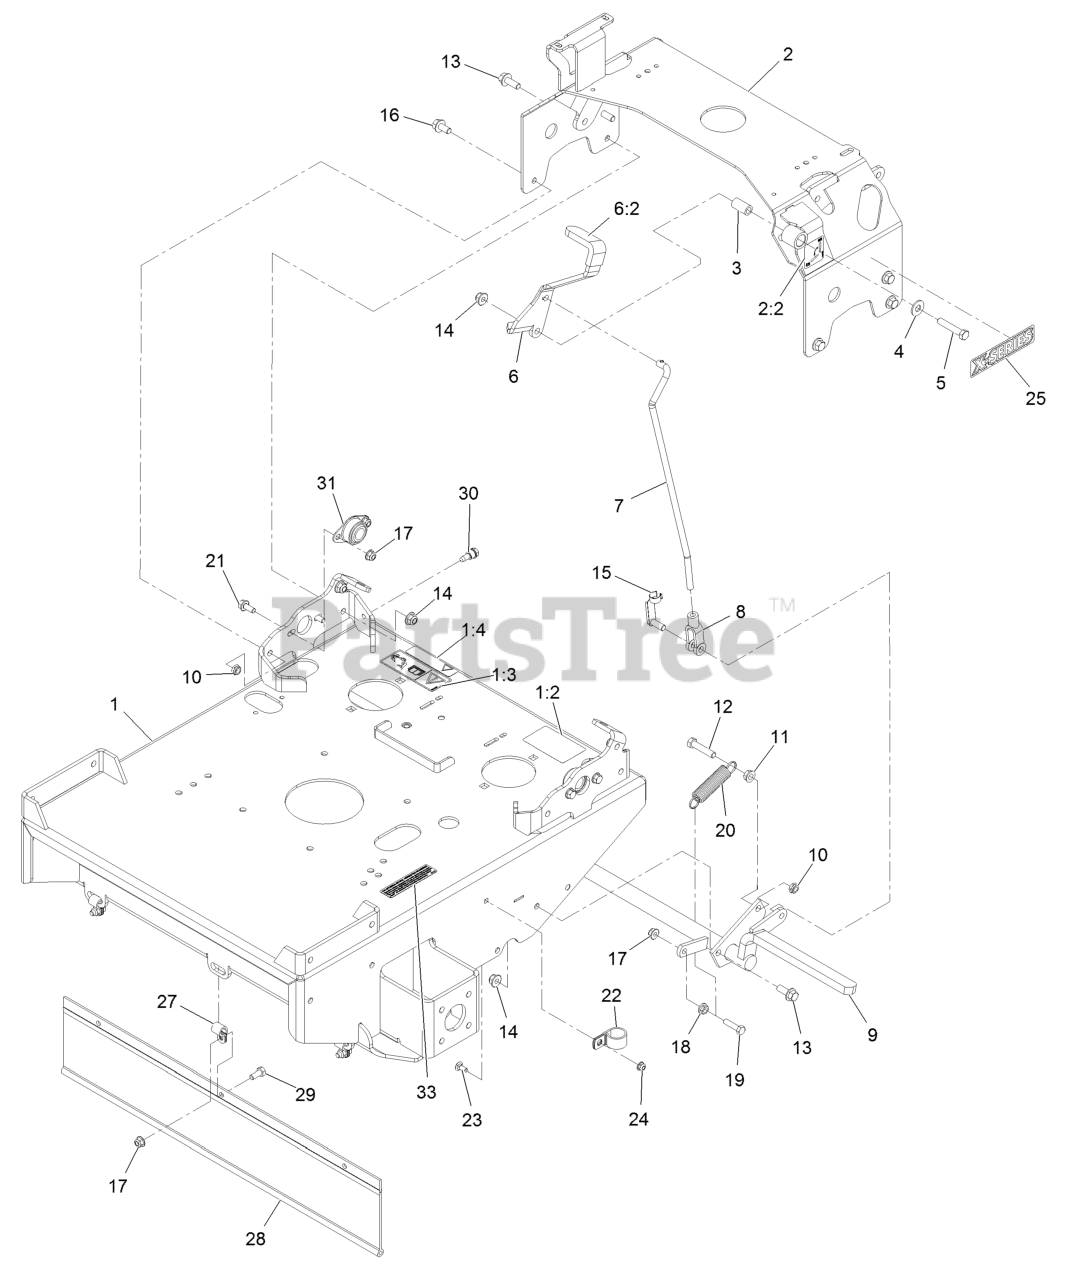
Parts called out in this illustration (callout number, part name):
1	ASM, ENGINE DECK W/ DECAL
1:2	DECAL-WARNING
1:3	DECAL-WARNING, SULKY
1:4	DECAL-DRIVE RELEASE
2	ASM, TANK SUPPORT W/ DECA
2:2	DECAL-PARK BRAKE, CE
3	BUSHING-PIVOT
4	WASHER-FLAT
5	SCREW-HH
6	ASM, BRAKE LEVER W/ GRIP
6:2	GRIP-LEVER
7	LINKAGE-BRAKE
8	YOKE-LINKAGE, BRAKE
9	WLD,BRAKE TTX
11	NUT-HHF, WHIZ
12	SCREW-HH
13	SCREW-HHF 3/8-16 X 1
14	NUT-HF, NI
15	PIN-SPRING, CLEVIS
16	SCREW-HHF
17	NUT-HF, NI
19	SCREW-HH
20	SPRING-IDLER
21	SCREW-HHF
22	CLIP-LOOM
23	SCREW-CARR
25	DECAL-X-SERIES
27	CLIP-LOOM
28	SHIELD,DRAG
29	SCREW-HH
30	BOLT-SHOULDER
31	BEARING-FLANGE, SIDE
33	DECAL-ARRESTER, SPARK
